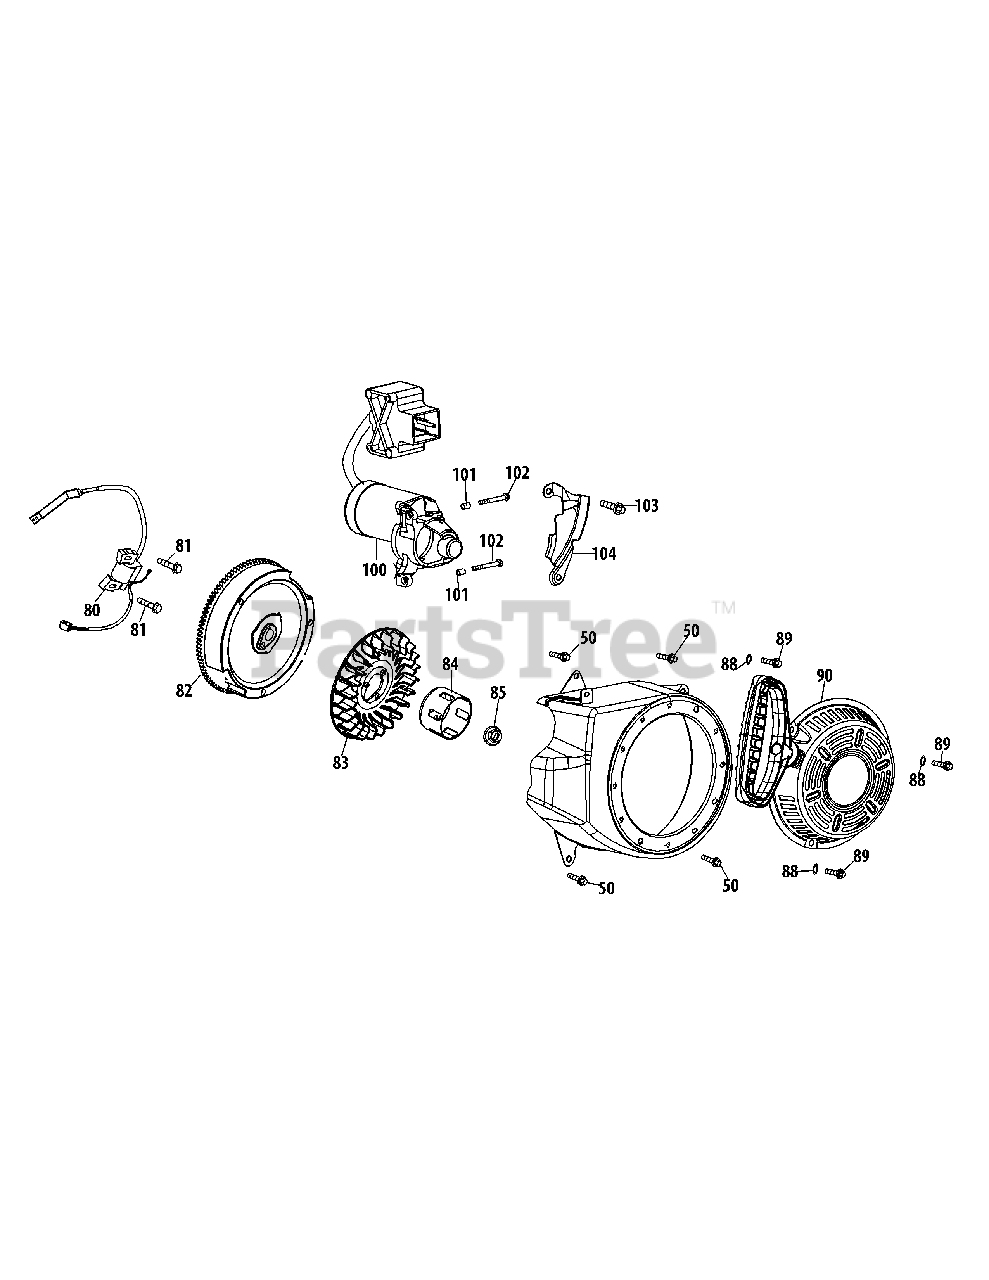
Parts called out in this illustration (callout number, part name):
50	Bolt M6×12
80	Ignition Coil Assembly
81	Bolt M6×25
82	Flywheel
83	Fan, Cooling
84	Starter Cup
85	Nut, Special, M14×1.5
87	Blower Housing
88	Washer
89	Bolt M6×10
90	Recoil Starter
100	Electric Starter
101	Dowel Pin 8×8
102	Bolt M6×32
103	Bolt M6×18
104	Blower Housing Shield
